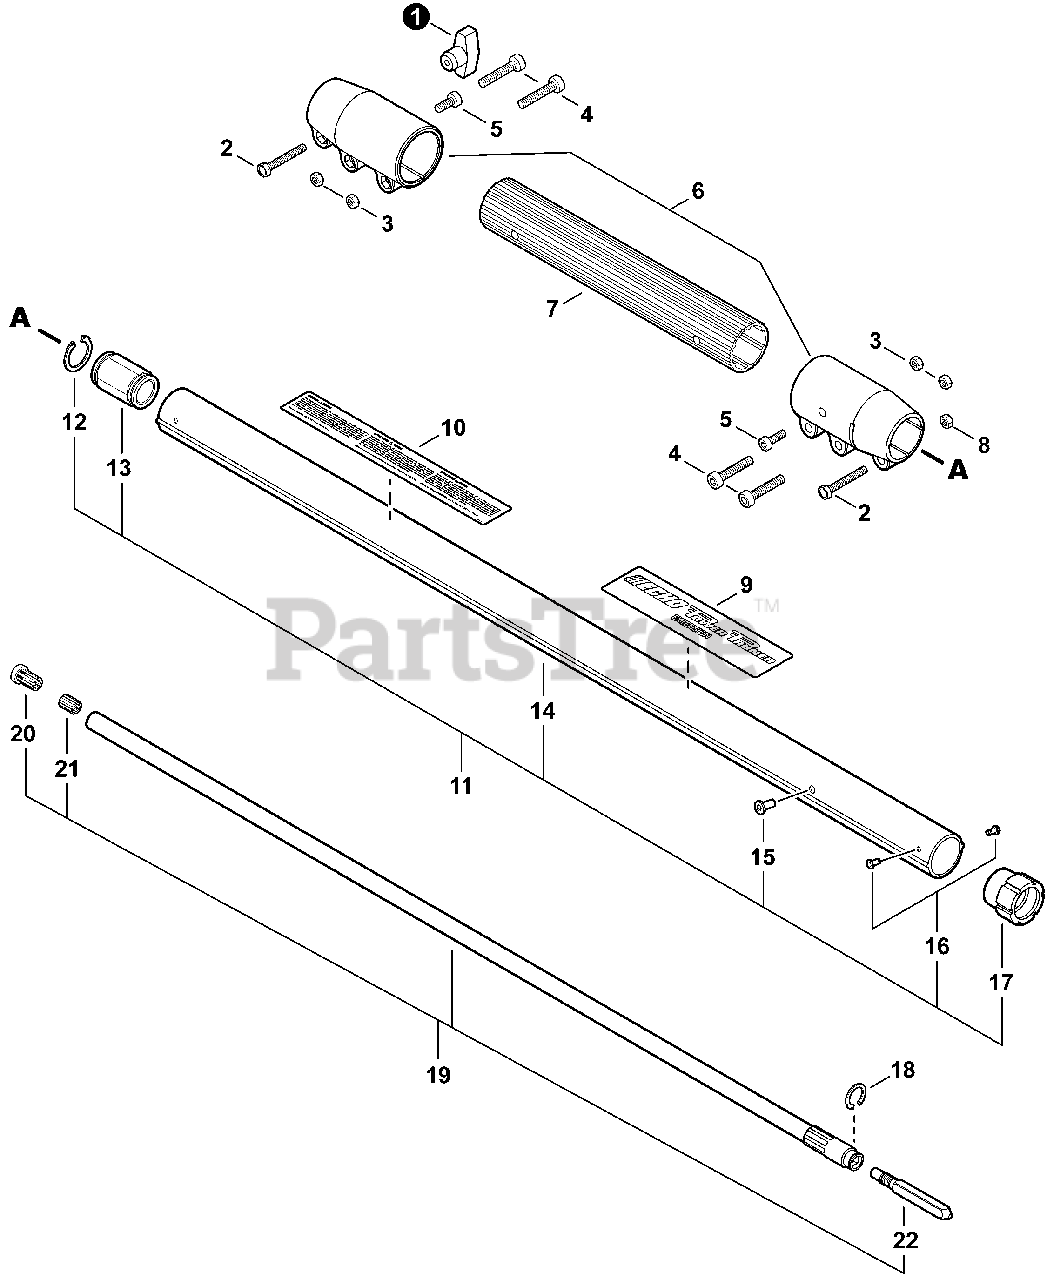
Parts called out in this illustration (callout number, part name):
1	THUMBSCREW
2	BOLT 6×25
4	BOLT 5×20
5	BOLT 5×12
6	COUPLING
7	PIPE, MAIN
8	NUT, HEX M6
9	LABEL, ECHO
10	LABEL, CAUTION
11	MAIN PIPE ASSY
12	RING, RETAINING
13	GUIDE, SHAFT
14	MAIN PIPE
17	HOLDER ASSY, BEARING
18	RING, RETAINING
19	DRIVESHAFT ASSY
20	SOCKET - OUTER
21	SOCKET - INNER
22	CONNECTOR, DRIVE SHAFT
